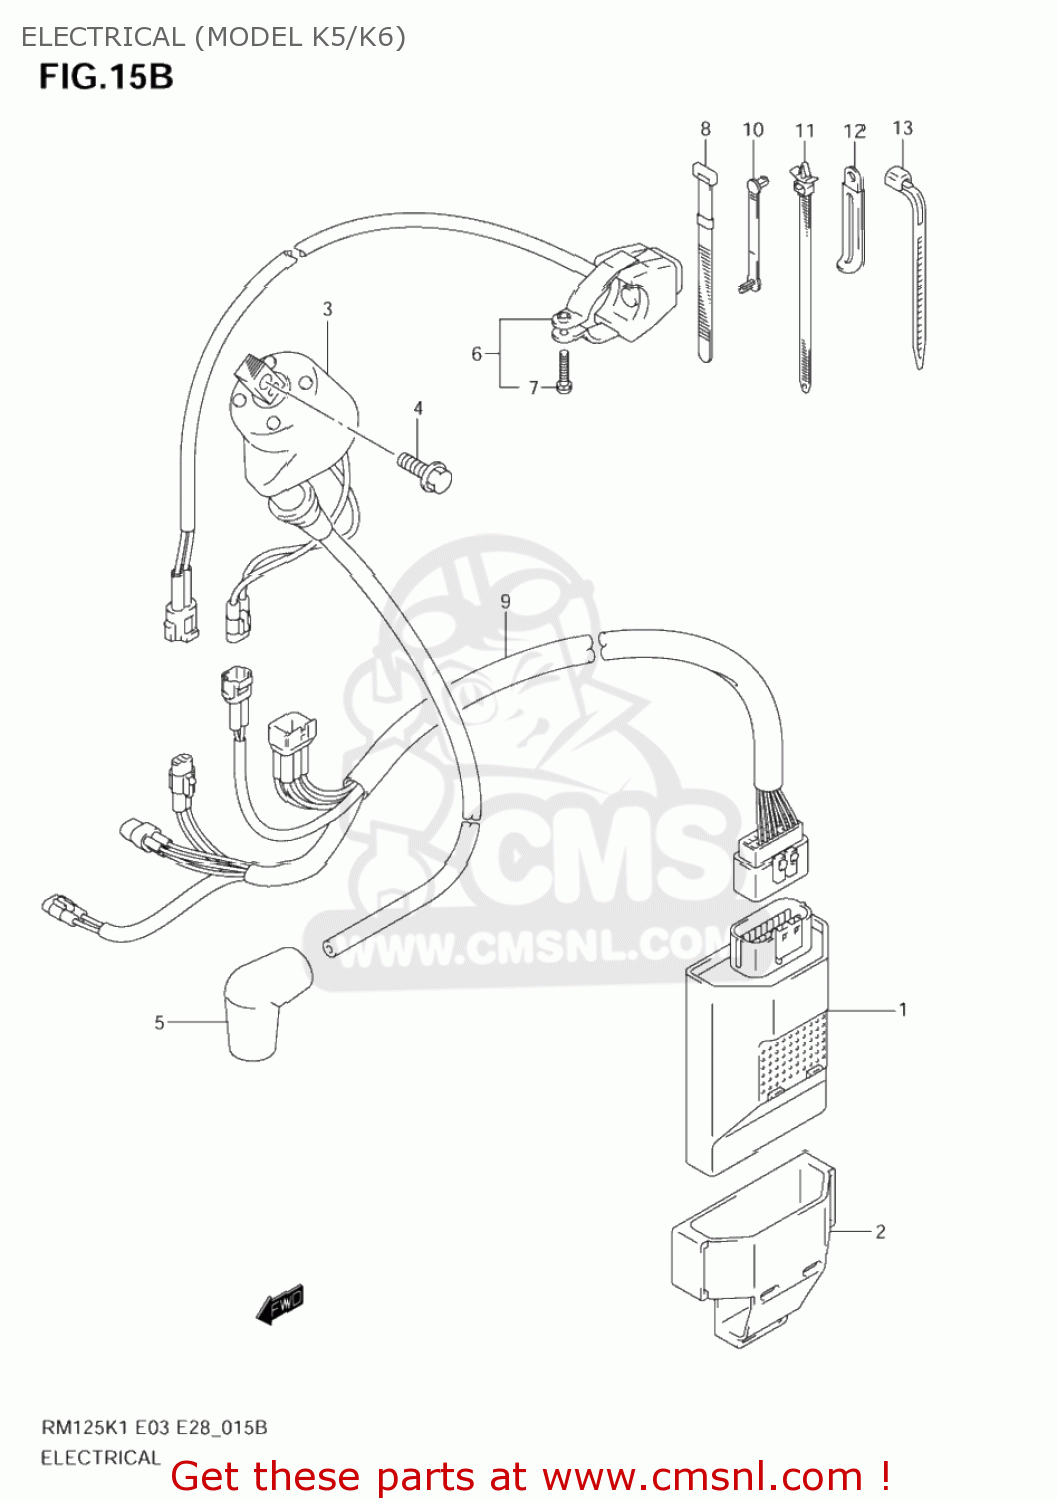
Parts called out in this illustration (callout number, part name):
1	CDI UNIT
2	CUSHION,CDI UNIT
3	COIL ASSY,IGNITION
4	BOLT(6X16)
5	CAP,SPARK PLUG
6	SWITCH ASSY,ENGINE STOP
7	SCREW
8	CLAMP(L:120)
9	HARNESS,WIRING
10	CLAMP(L:63)
11	CLAMP(L:90)
12	CLAMP(L:45)
13	CLAMP(L:95)
